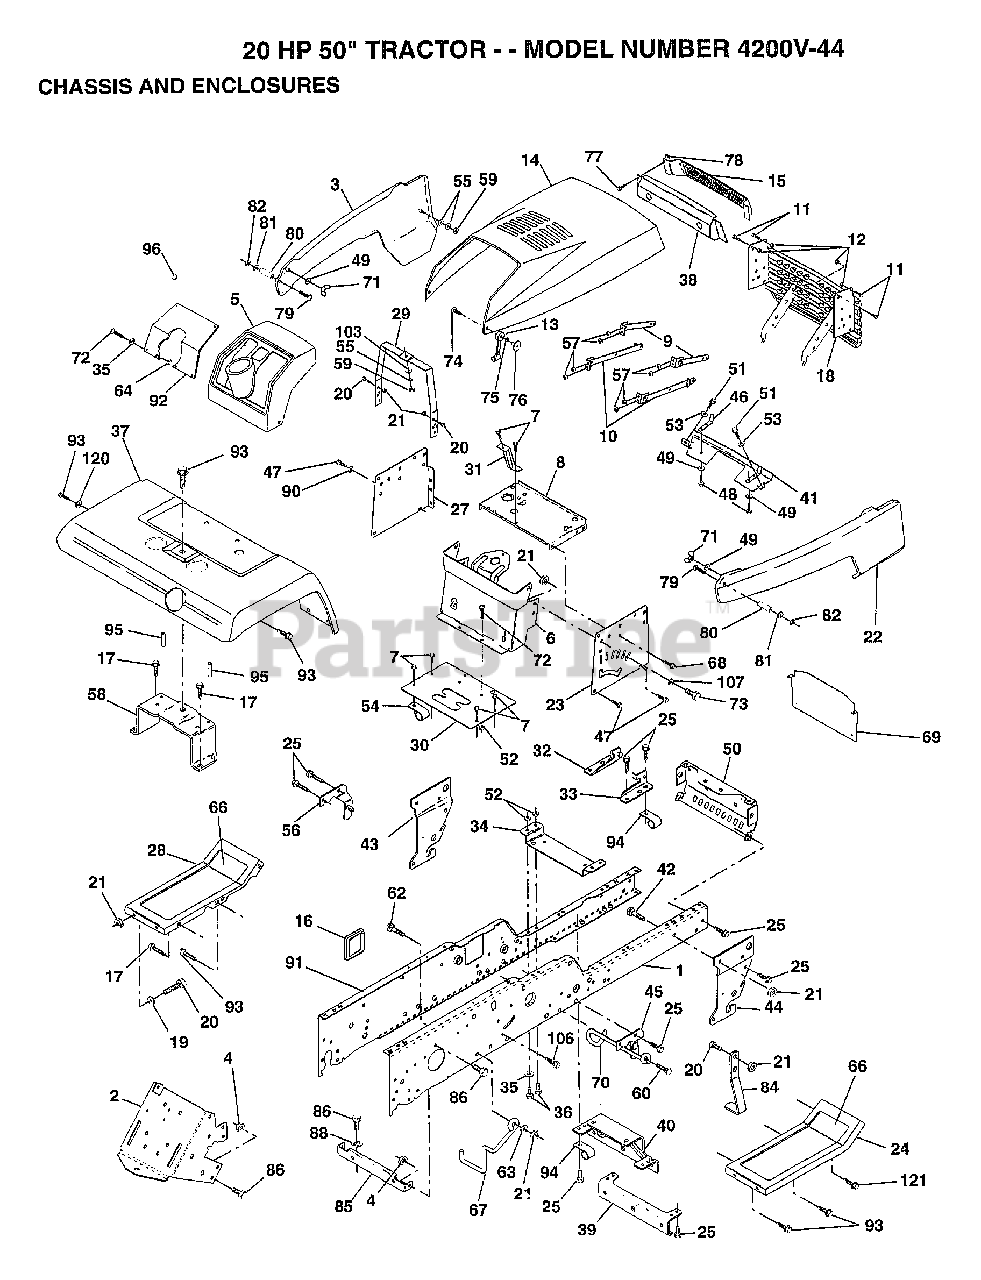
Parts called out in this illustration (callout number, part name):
2	DRAWBAR GT
3	PANEL SIDE LH
4	NUT.7/16
5	DASHBOARD BLACK
6	DASH ASM LOWER
7	SCREW
8	SUPPORT BATRY VGT
12	NUT
13	HOOD LATCH T
15	LENS LT
16	COVER ACCESS
17	SCREW
18	GRILLE.ASM.PNT.YP
19	WASHER
20	BOLT
21	NUT
25	SCREW
29	SUPPORT ASS'Y
30	SADDLE SILKSCRN
31	BRACE.SUPT.STRG
32	BRACKET ASM FRAME
33	BRACKET ASM FRAME
35	WASHER
36	BOLT
39	BRACKET.AXLE.FRT.
43	BRACKET.SUS.FT.LH
44	BRACKET.SUS.FT.RH
47	SCREW LT
48	SCREW
49	WASHER
50	BRACKET.CHASSIS.
51	SCREW HEX CRT
52	NUT
53	WASHER
54	"CLIP,INSULATOR"
55	WASHER PM
57	NUT
58	BRKT.ASM.FENDER
60	SCREW
62	BOLT D
63	WASHER
66	FOOTREST PAD
67	GUIDE BELT TRANS
68	SCREW LT
69	SHIELD.HEAT.VGT.
70	GUIDE.BELT.MID.SP
72	SCREW
73	BOLT
74	SCREW
75	LOCKWASHER
76	WELDNUT
78	"""J"" FASTENER LT"
79	SCREW
80	SPACER LT
81	WASHER
84	STOP.OVER.CENTER
86	BOLT
88	LOCKWASHER
90	LOCKWASHER
92	PLATE DASH SILKSC
93	SCREW LT
94	CLIP GTV
95	NUT-PUSH YT
96	PLUG-DASH T
103	LOCKWASHER
106	BOLT.5/16-18X1.25
107	WASHER
120	WASHER HYT
121	SCREW GTV
